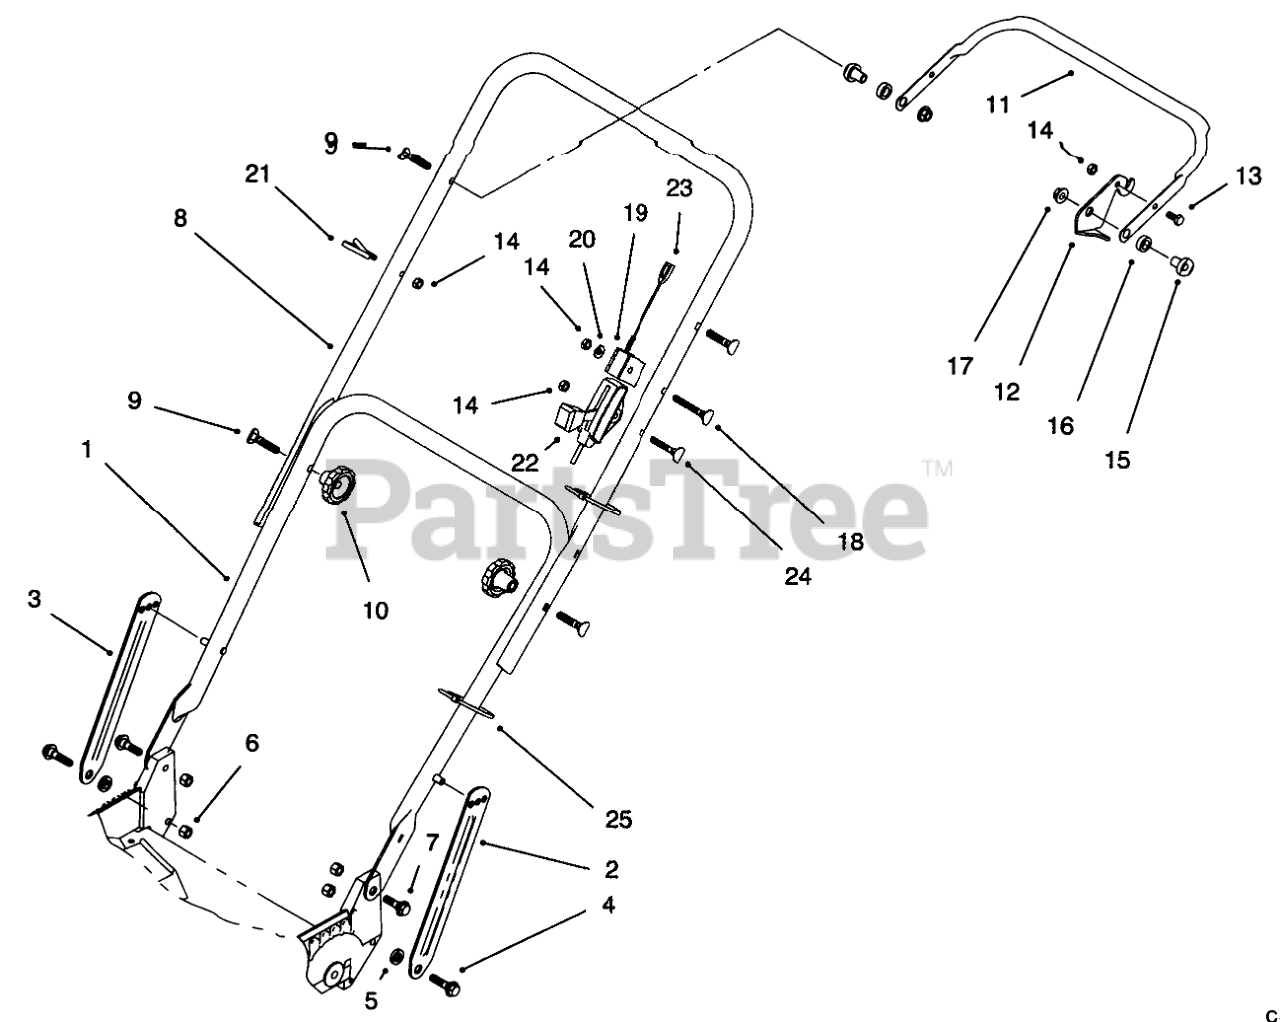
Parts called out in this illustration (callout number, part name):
1	ASM-Handle
2	Latch-Handle
3	Latch-Handle
4	SCREW-SHOULDER
5	SPACER
6	NUT-LOCK, NI
7	SCREW-SHOULDER
8	Handle-Upper
9	SCREW-HANDLE
11	Bar-Control
12	Lever-Control
13	SCREW-HH
14	NUT-LOCK, NI
15	SPACER-SUPPORT
16	SPACER-NYLON
17	NUT-LOCK NI
18	SCREW-HANDLE
19	SUPPORT-CABLE
20	WASHER-FLAT
21	GUIDE-ROPE
22	CONTROL - THROTTLE
23	CABLE - BRAKE
24	SCREW-HANDLE
25	TIE-CABLE
